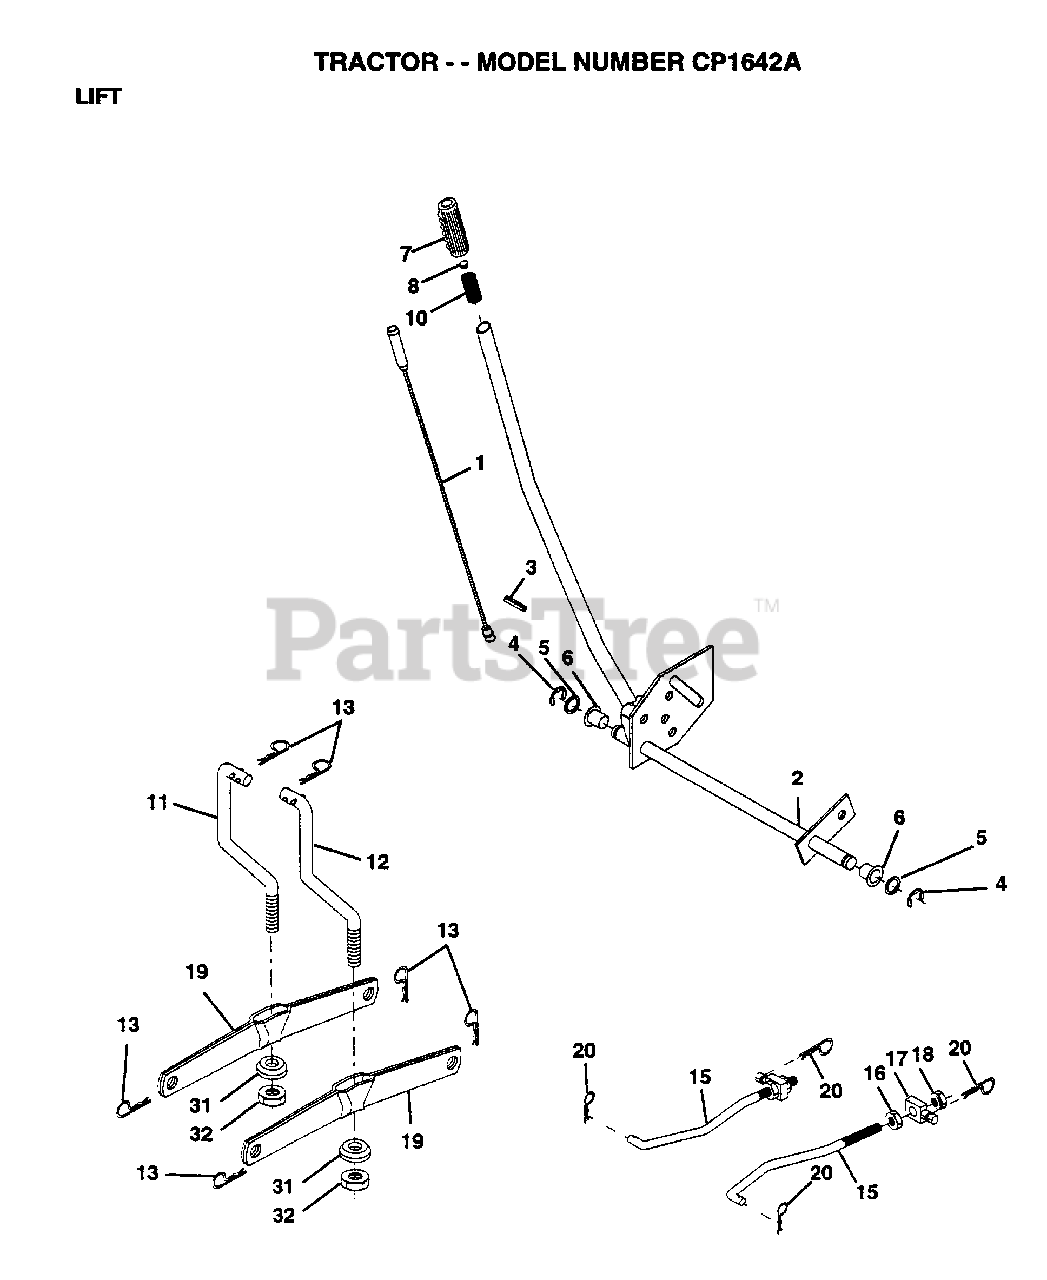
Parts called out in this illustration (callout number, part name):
1	WIRE ASM
2	HANDLE.LIFT.LH.
3	PIN GROOVE
5	WASHER
6	NYLON BEARING
7	GRIP
15	LINK.FRONT
16	NUT
17	TRUNION
18	NUT.LK.W/WSH.1/2.
19	ARM SUSP REAR
20	RETAINER.SPRING
31	BEARING PVT LH
32	NUT.CROWNLOCK.3/8
